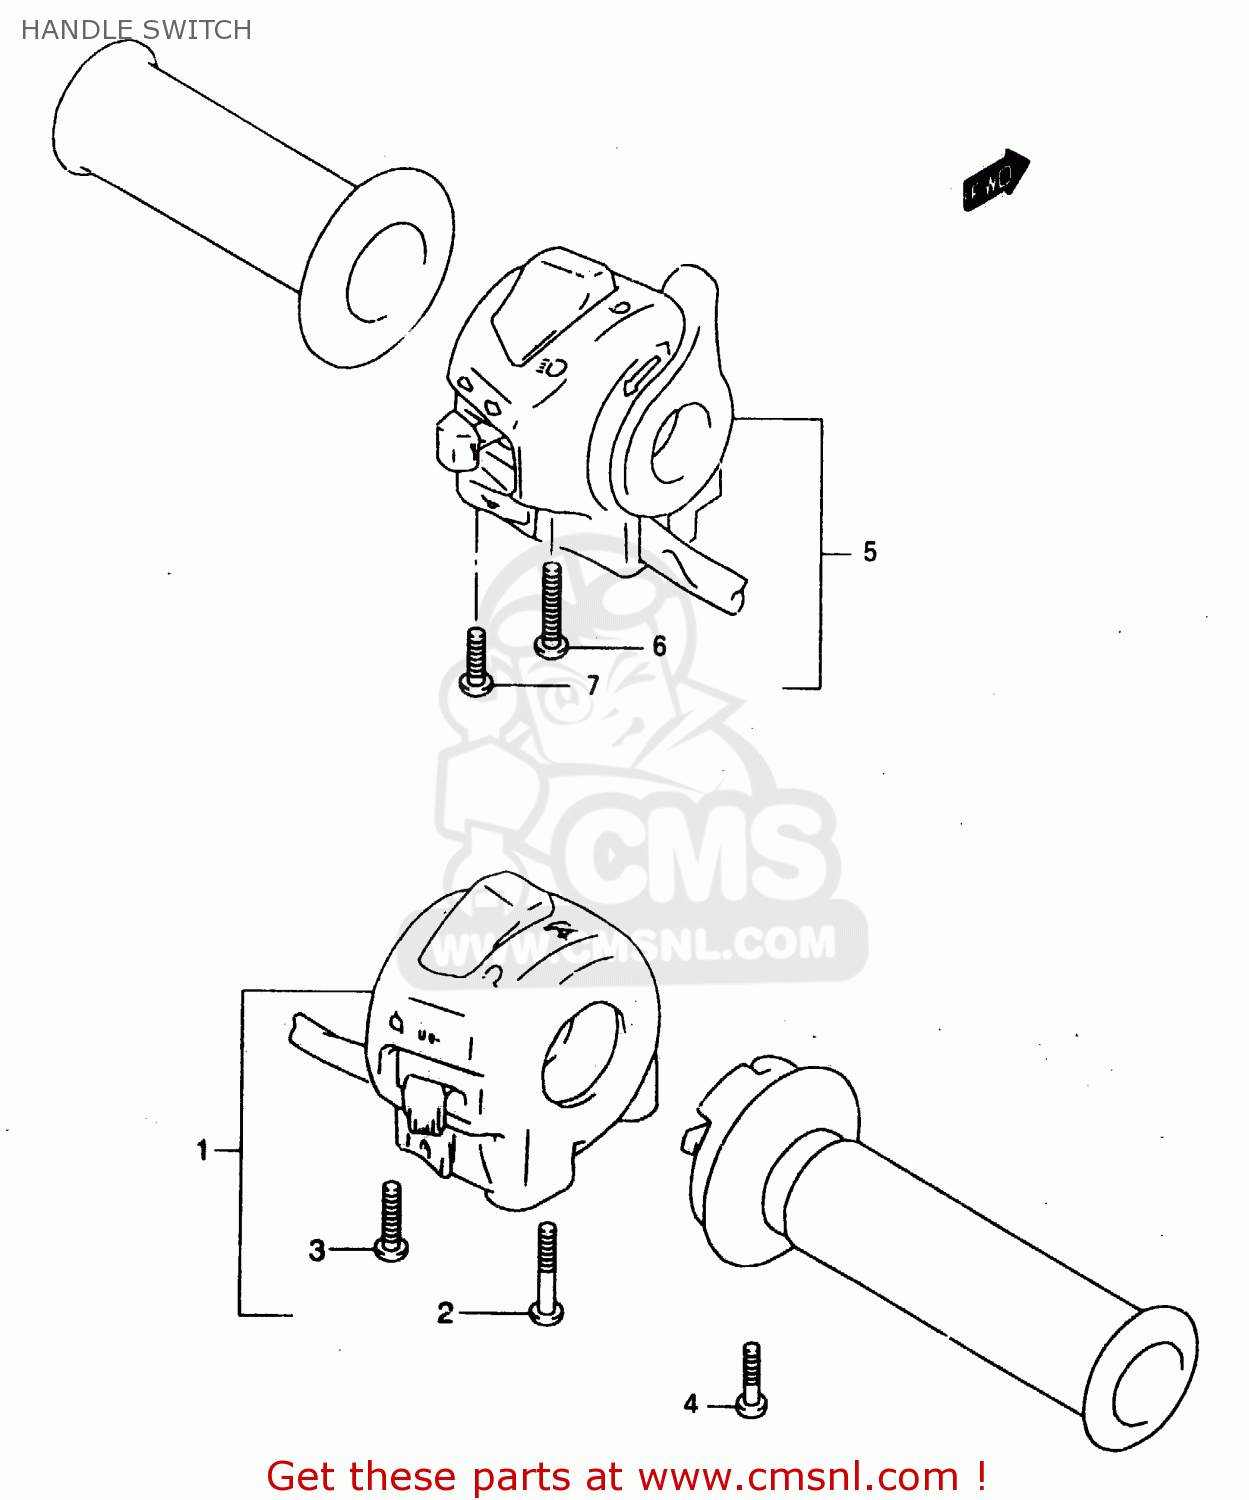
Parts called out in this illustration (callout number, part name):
1	SWITCH ASSY,HANDLE,R
2	SCREW
3	SCREW
4	SCREW
5	SWITCH ASSY,HANDLE,L
6	SCREW
7	SCREW
